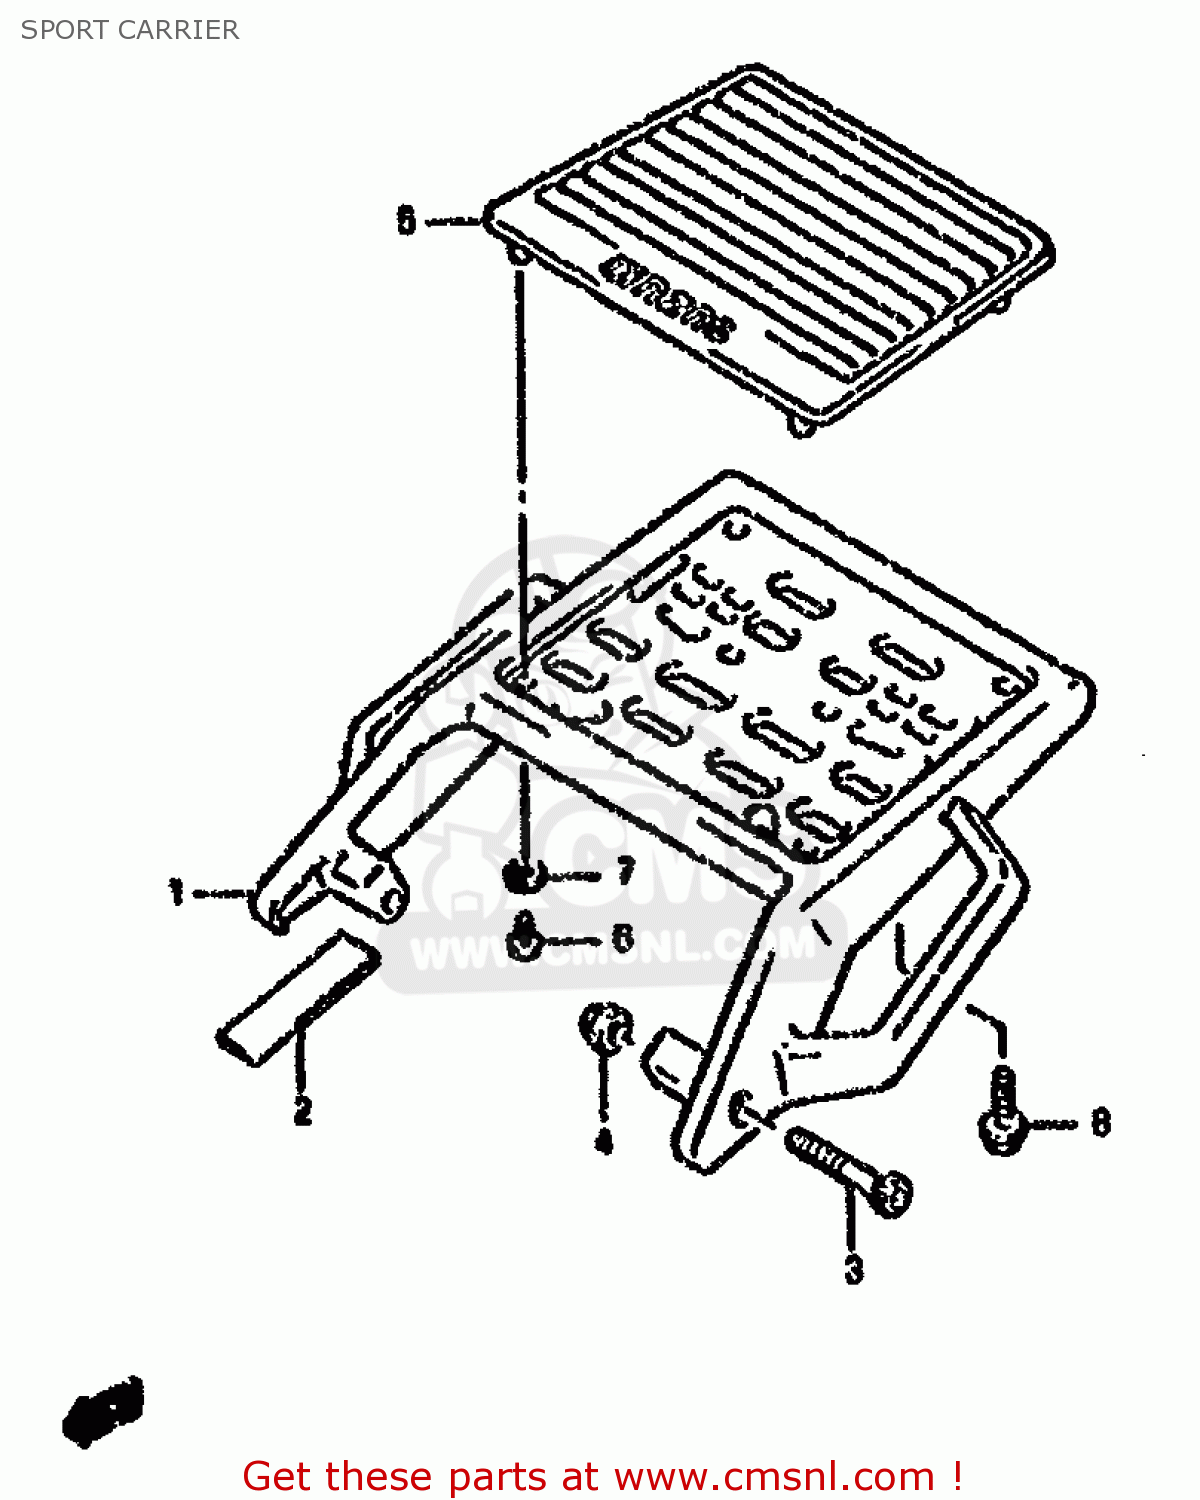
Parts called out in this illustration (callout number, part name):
1	CARRIER,SPORT
2	CUSHION,FR
3	BOLT
4	NUT
5	MAT,SP.CARRIER
6	SCREW
7	WASHER(6.5X18X1)
8	BOLT
